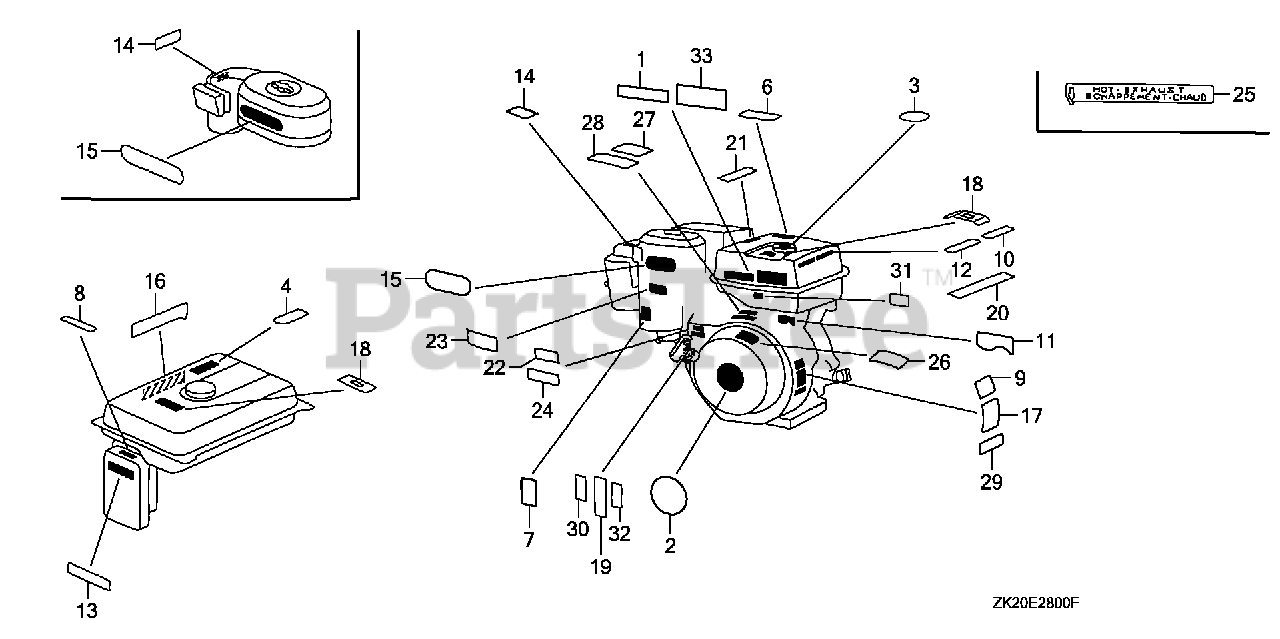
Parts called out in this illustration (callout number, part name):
1	LABEL, CAUTION (ENGLISH, ETC.)
2	EMBLEM (GX240)
3	MARK, CAUTION
7	MARK, CHOKE (ORANGE)
9	LABEL, SPECIFICATION (EXTERNAL)
10	MARK, OIL ALERT (GERMAN)
10	MARK, OIL ALERT (FRENCH)
11	MARK, OIL ALERT (EXTERNAL)
12	MARK, OIL ALERT (ENGLISH)
